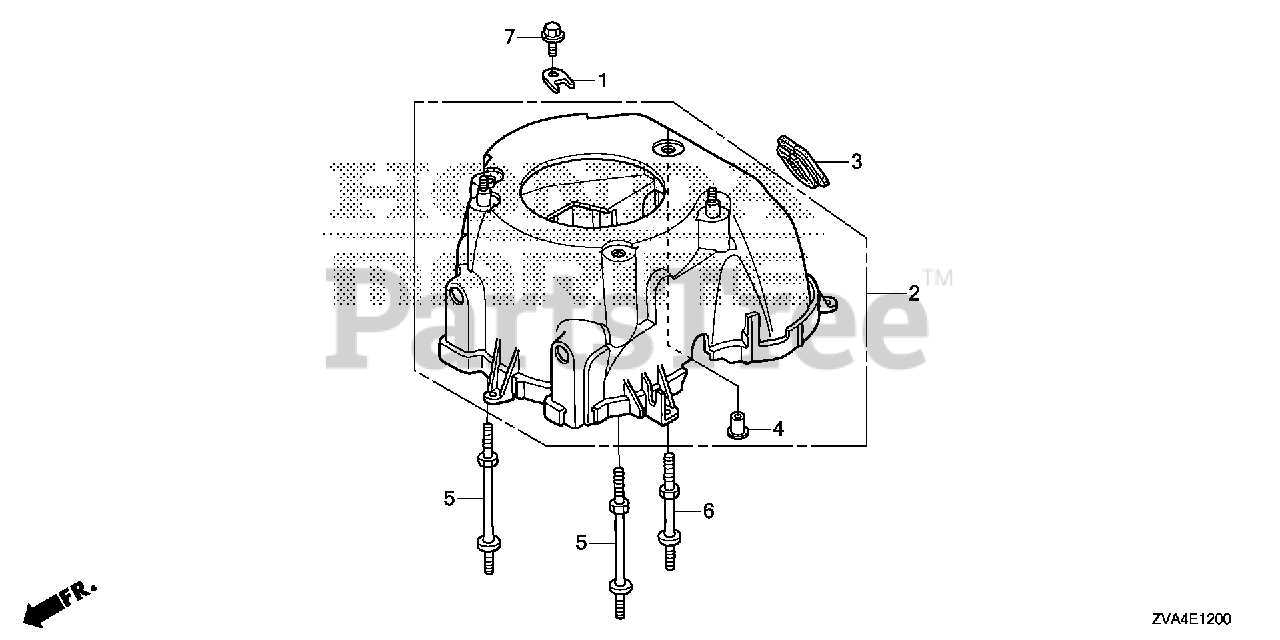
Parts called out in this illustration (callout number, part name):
1	HOLDER, CABLE
2	COVER, FAN
3	GROMMET, FAN COVER
4	COLLAR, FAN COVER
5	BOLT A, STUD
6	BOLT B, STUD
7	BOLT, FLANGE (5X10)
